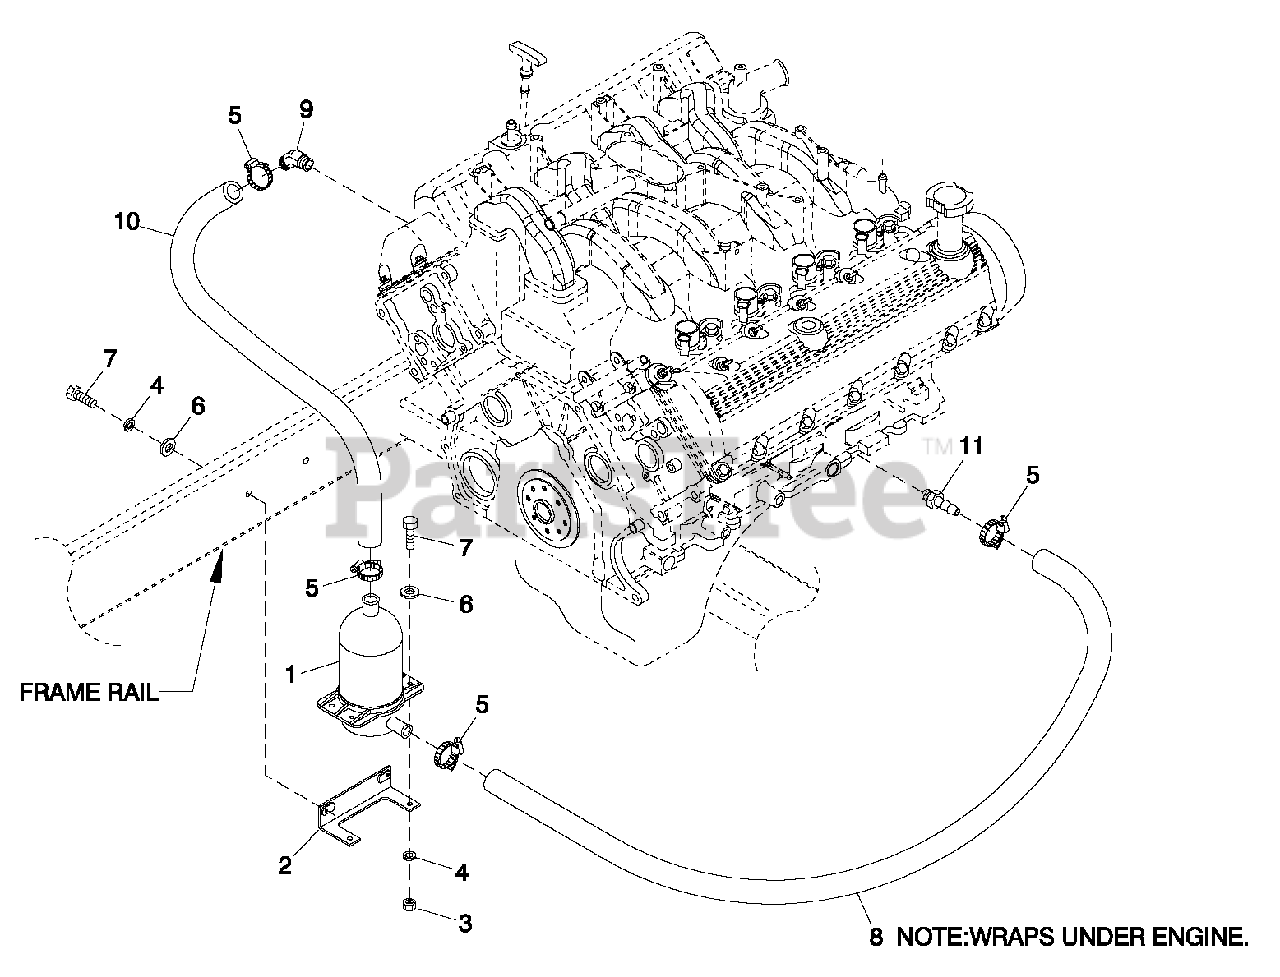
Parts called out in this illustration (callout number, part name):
1	HEATER BLOCK 2000W 240V
2	BRACKET HEATER W/WELDNUTS
3	NUT HEX M6X 1.0 G8YEL CHR
4	WASHER LOCK M6-1/4
5	CLAMP HOSE #8.53-1.00
6	WASHER FLAT 1/4-M6 ZINC
7	SCREW HHC M6-1.0X 20 G8.8
8	HOSE COOL 5/8 ID 20R3 (24" LG)
9	BARBED EL 45 3/8 NPT X 5/8 OD
10	HOSE PREFORMED BLOCK HEATER
11	BARBED STR 3/8 NPT X 5/8
